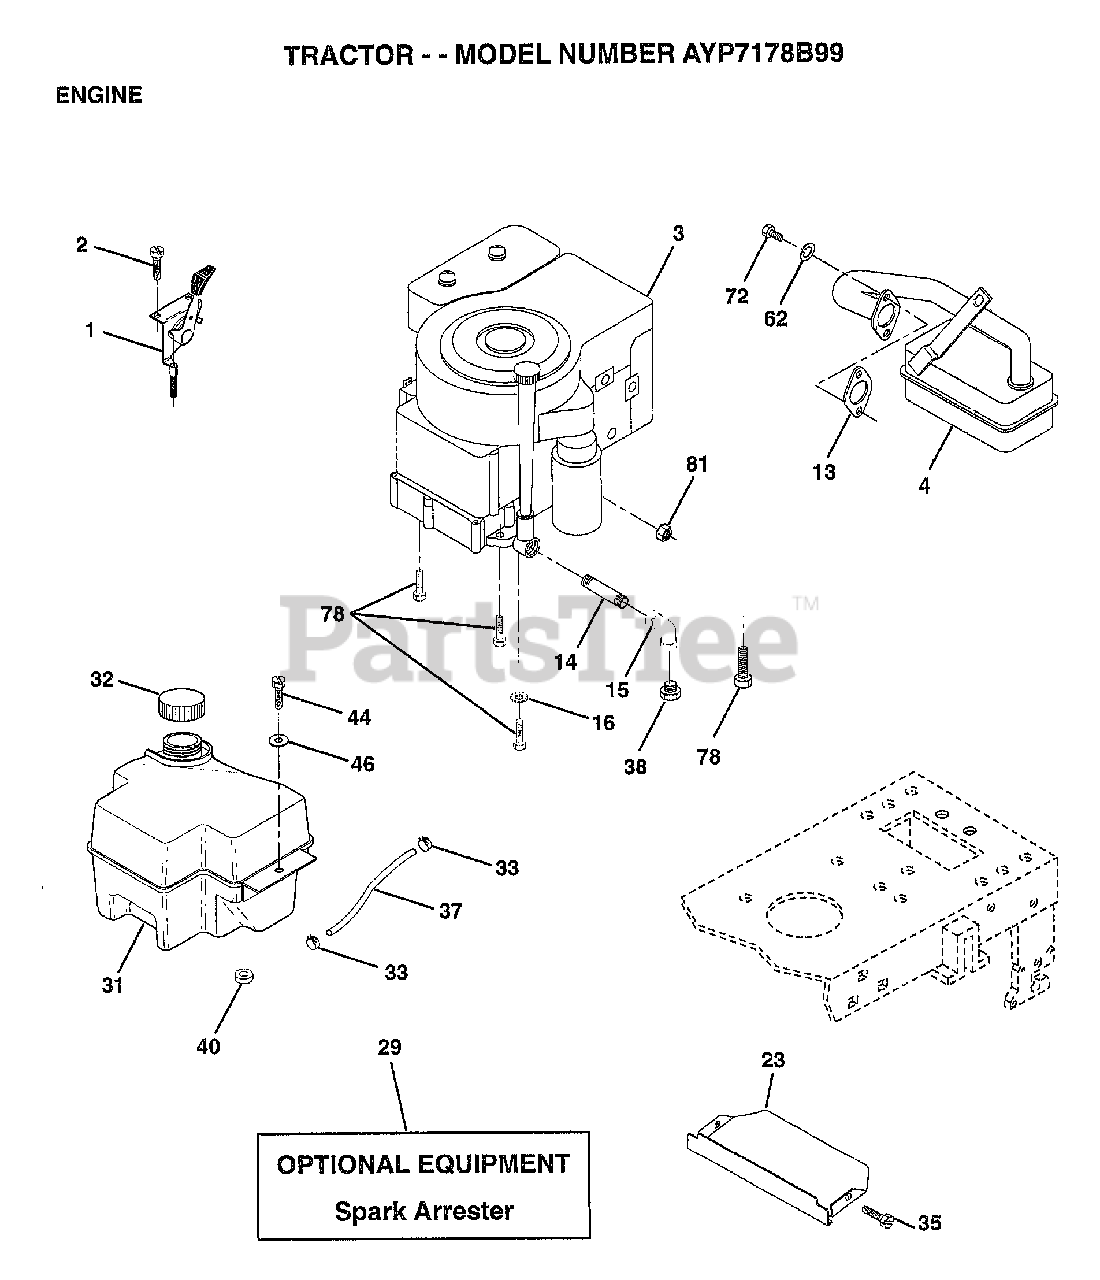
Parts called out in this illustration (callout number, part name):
1	CONTROL THROTTLE
2	SCREW LT
4	MUFFLER
13	GASKET ENG 1 313 LD TIN PLATED
14	PIPE NIPPLE
15	ELBOW
16	LOCKWASHER
23	SHIELD.BRN/DBR.GD
31	TANK.FUEL.FRONT.
32	CAP ASM FUEL
33	HOSE CLAMP
35	SCREW
37	LINE FUEL
44	SCREW HEX CRT
46	WASHER
62	LOCKWASHER
72	SCREW
78	SCREW
81	NUT
